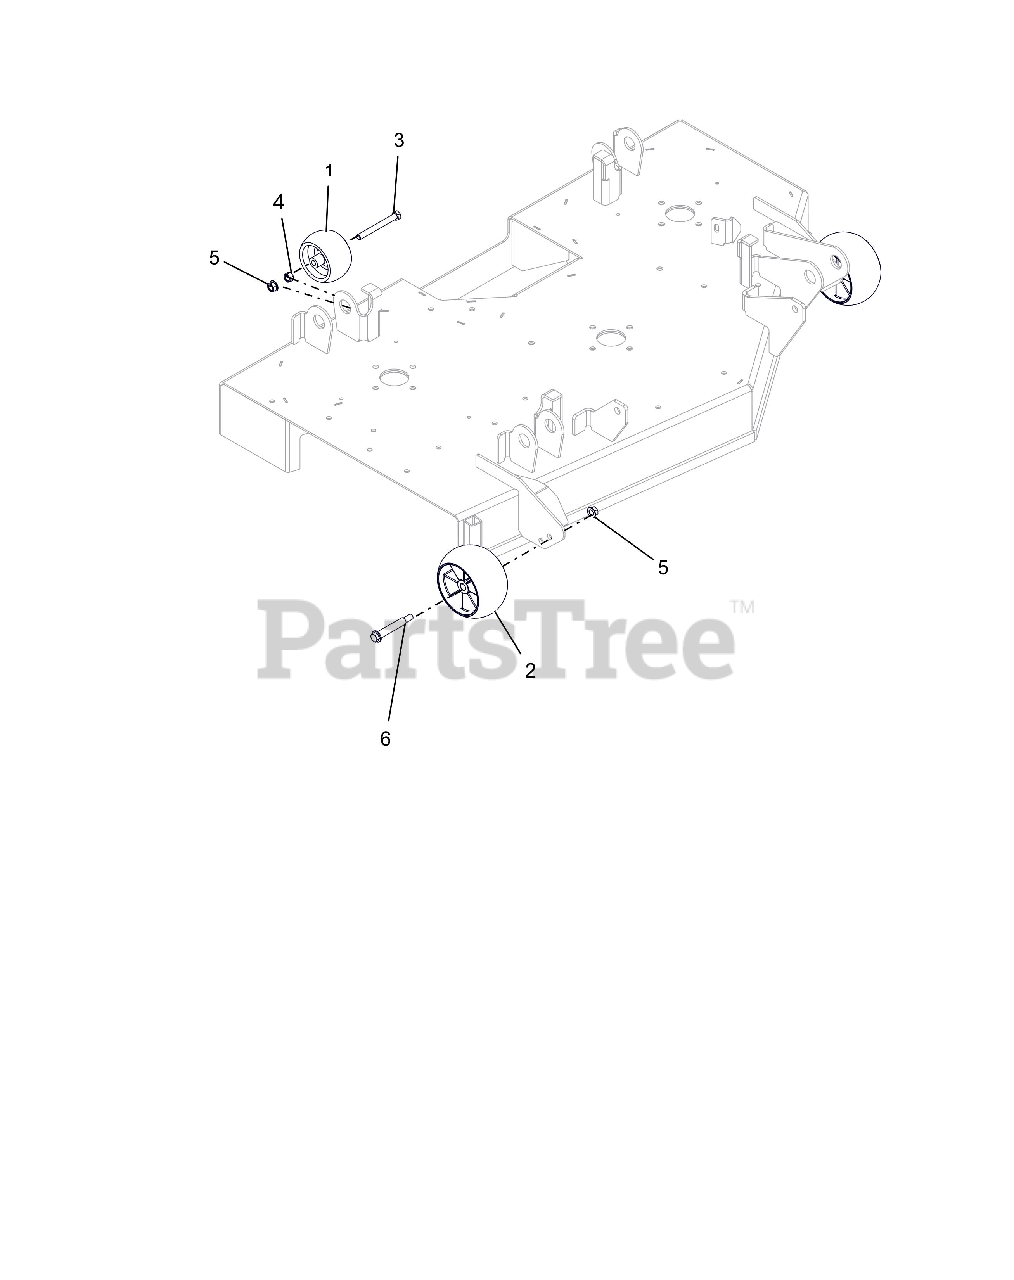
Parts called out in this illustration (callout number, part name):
2	ANTI-SCALP WHEEL - 5X OS
3	@BLT-HEX .38-16X3.50 GR5 YWZC
4	@NUT-HEX .38-16 YWZC
5	@NUT-LK-TOP-FLG .38-16 YWZC
6	BLT-SHLDR .38-16X2.50 HWH G5
